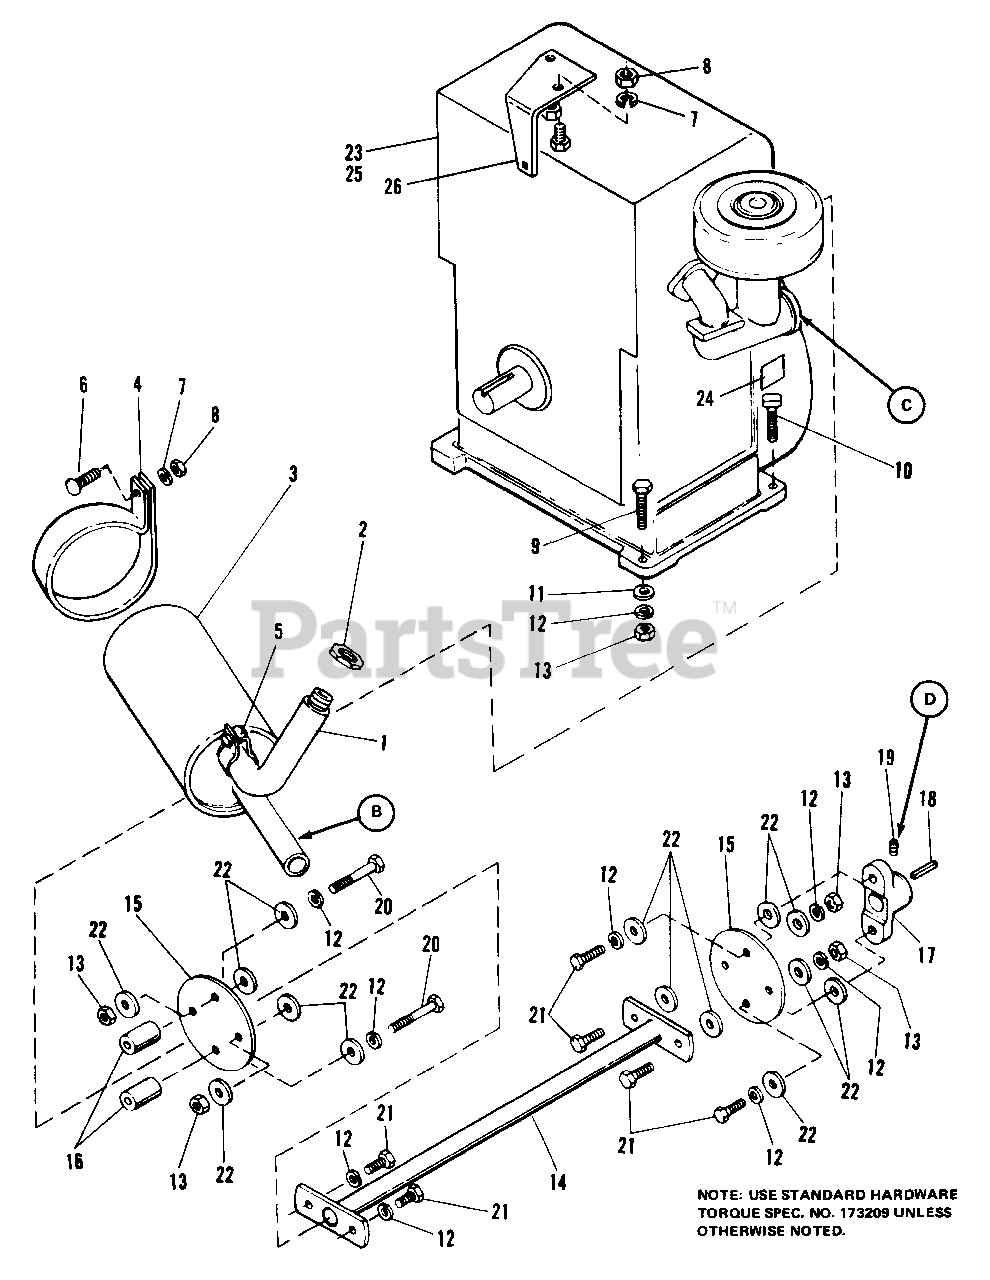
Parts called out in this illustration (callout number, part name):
1	ELBOW & NIPPLE ASSY
3	MUFFLER, Exhaust
4	STRAP, Muffler
5	CLAMP, Muffler
6	BOLT, Carriage, 5/16-18 x 1-1/4
7	LOCKWASHER, 5/16
8	NUT, Hex, 5/16-18
9	CAPSCREW, Hex, Hd., 3/8-16 x 1-1/2
10	CAPSCREW, Rect. Hd., 3/8-16 x 1-5/16
11	WASHER, 3/8
12	LOCKWASHER, 3/8
13	NUT, Hex, 3/8-16
14	SHAFT ASSY, Drive
17	FLANGE, Drive Shaft
18	KEY, Drive Shaft
19	SETSCREW, 3/8-24 x 3/8
20	CAPSCREW, Hex Hd., 3/8-16 x 2-1/4
21	CAPSCREW, Hex Hd., 3/8-16 x 1-1/4
22	WASHER, Special
23	ENGINE, 14 H.P., Briggs & Stratton
24	FILM, Oil Level Instructions
25	DECAL, Caution
26	SUPPORT, Muffler
